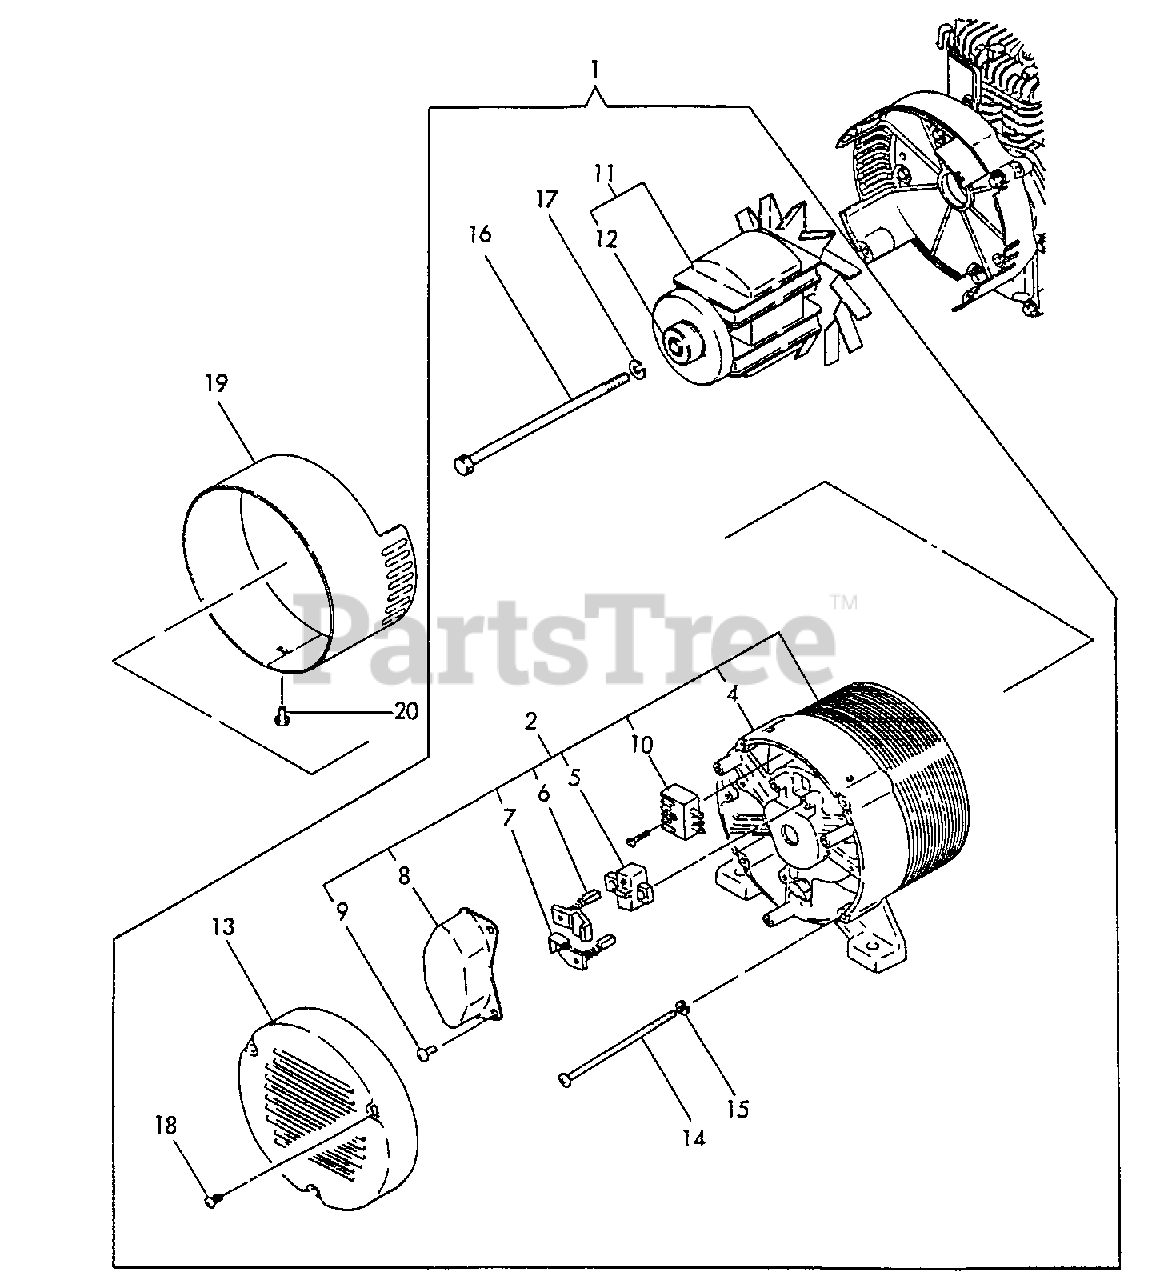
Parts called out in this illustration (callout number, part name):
1	GENERATOR 1.3 KVA
2	STATOR ASSY
4	COVER - REAR
5	HOLDER, BRUSH
6	BRUSH - ( + )
7	BRUSH - ( - )
8	A.V.R.
9	SCREW - 5X14
10	RECTIFIER
11	ROTOR ASSY
12	BEARING, BALL
13	COVER
14	BOLT
15	LOCKWASHER - 6
16	BOLT
17	LOCKWASHER - 8
18	SCREW - 4X8
19	BAND
20	BOLT - 6X8 -- PLATED
